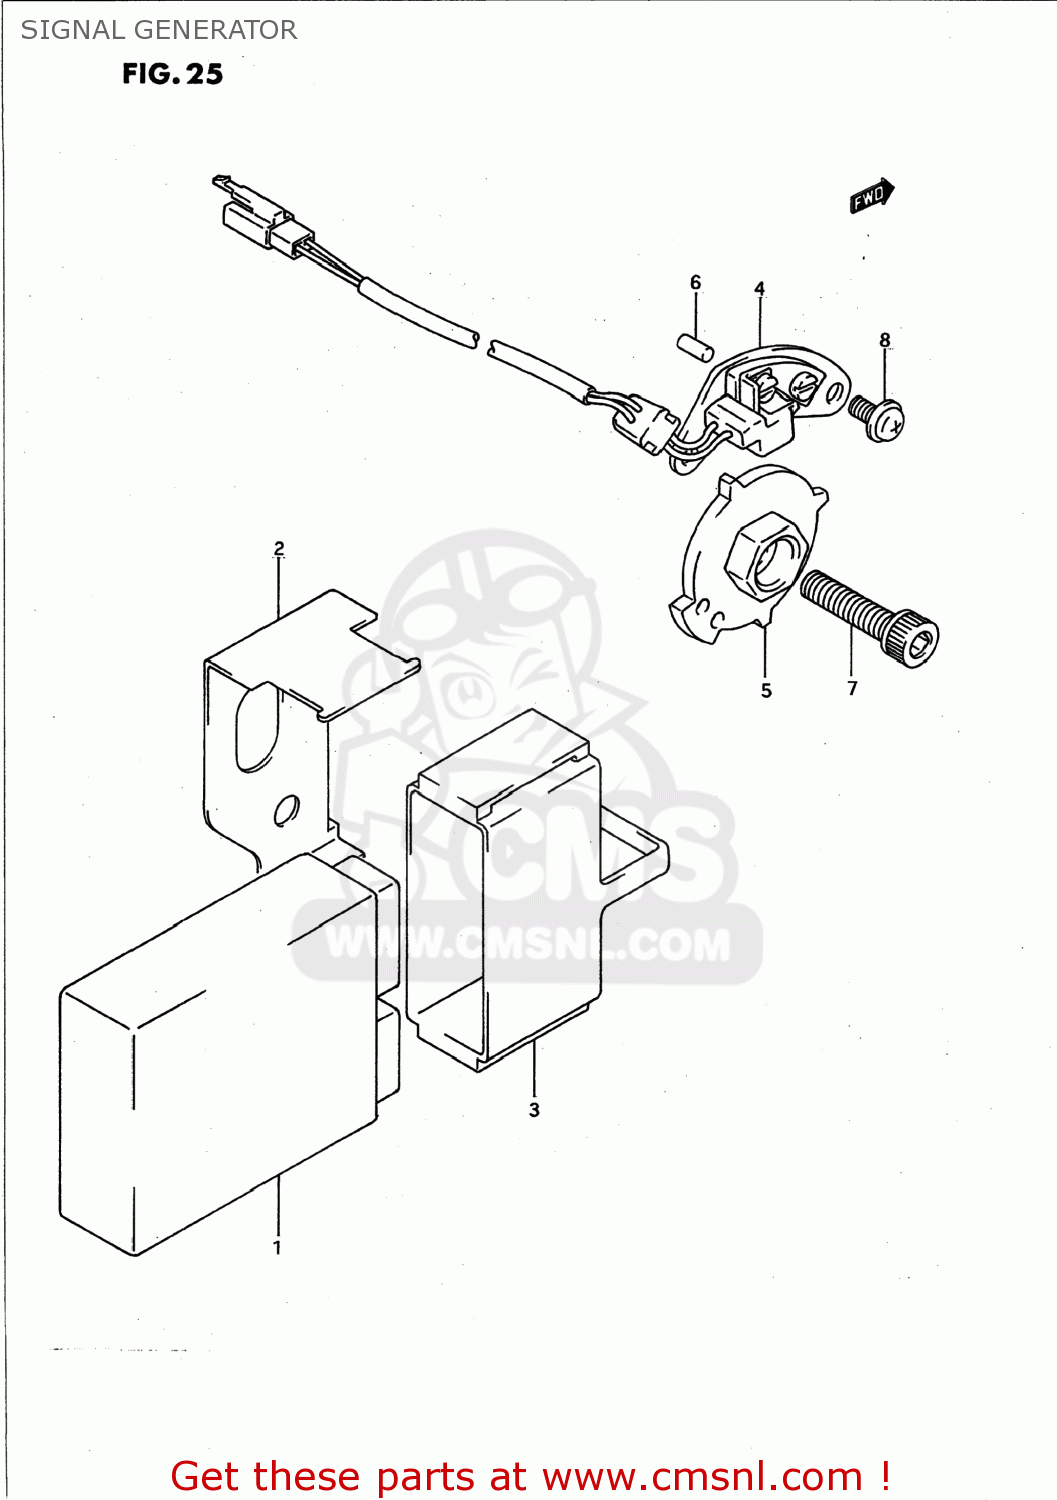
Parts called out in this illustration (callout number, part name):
1	IGNITER ASSEMBLY
2	BRACKET,IGNITOR
3	CUSHION,IGNITOR
4	STARTER,SIGNAL GENERATOR
5	ROTOR,SIGNAL GENERATOR
6	PIN
7	BOLT
8	SCREW
